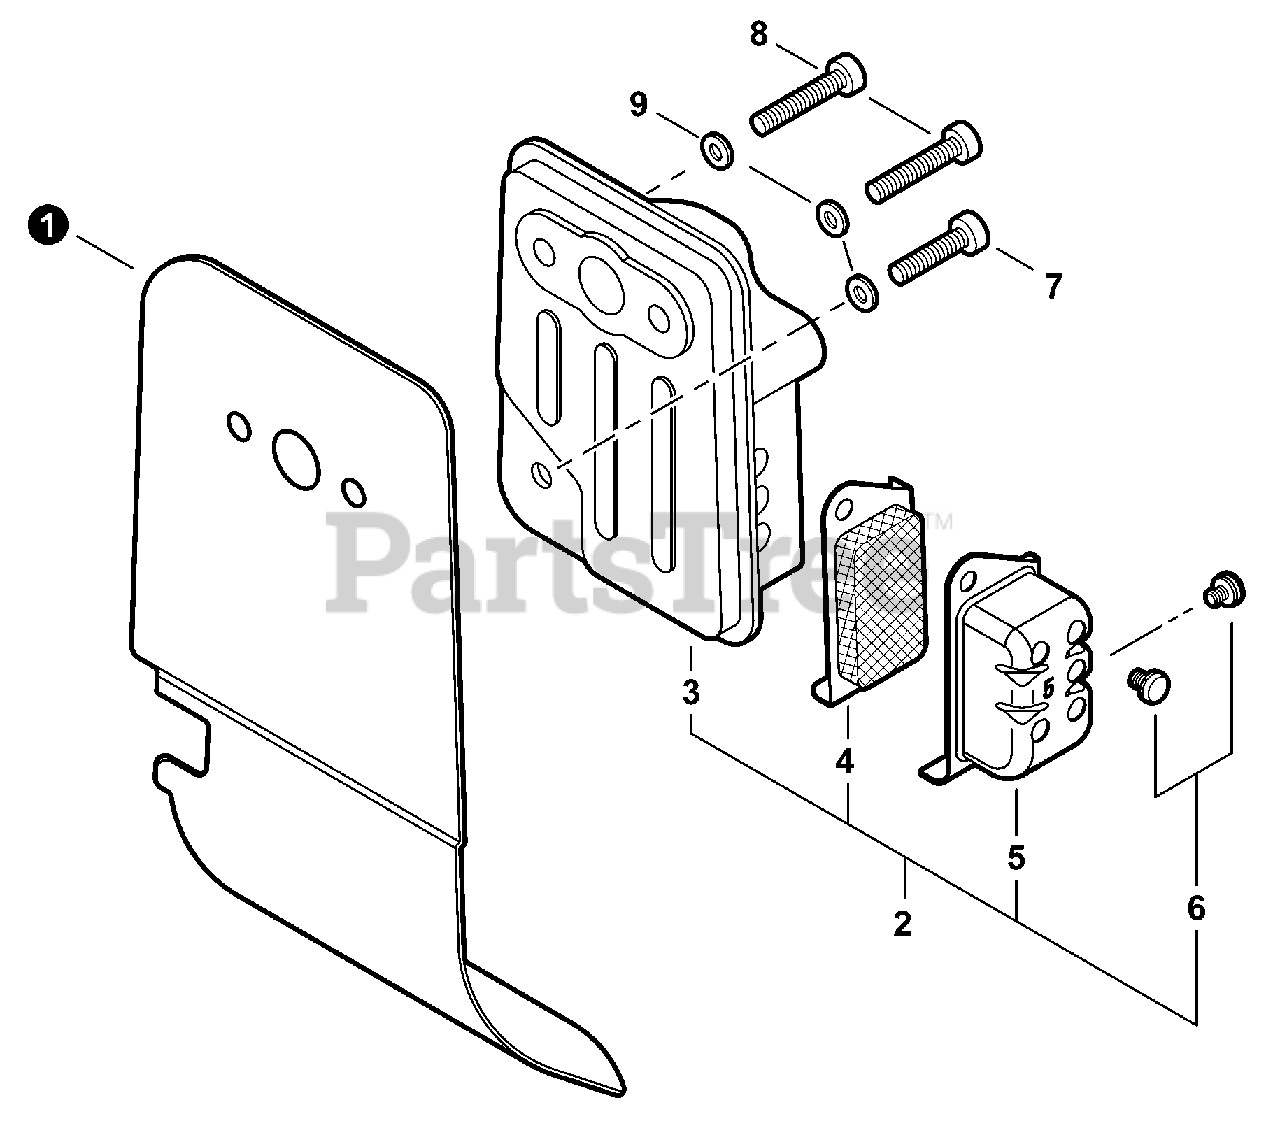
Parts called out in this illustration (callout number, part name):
1	HEAT SHIELD, EXHAUST
2	MUFFLER ASSY
3	MUFFLER
4	SCREEN, SPARK ARRESTER
5	GUIDE, EXHAUST
6	SCREW M4x6
7	BOLT 5x16
8	BOLT M5x25
9	WASHER, FLAT 5.5x10x0.8
